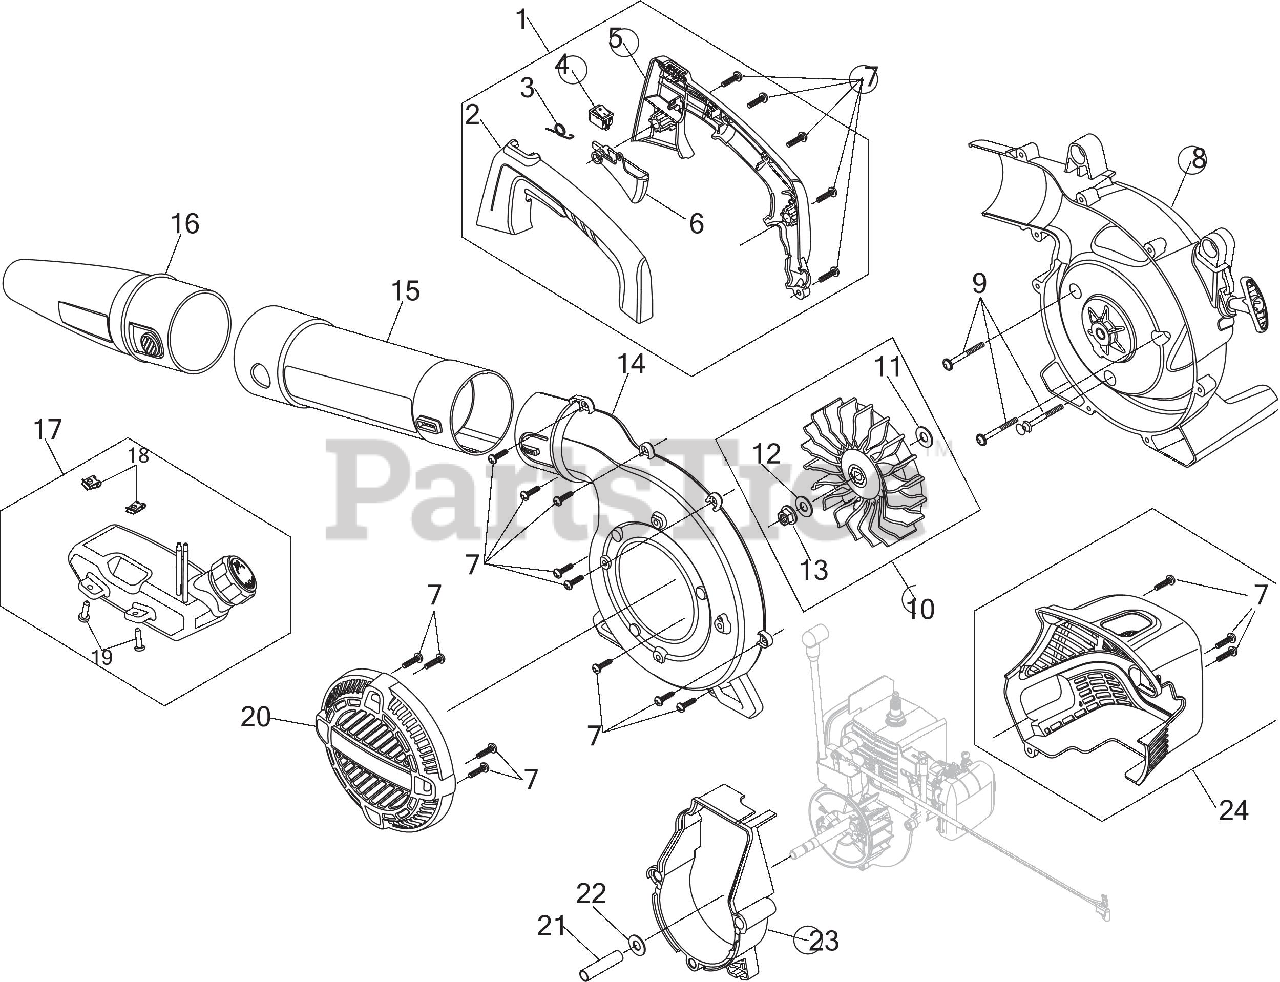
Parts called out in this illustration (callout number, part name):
1	HANDLE ASSEMBLY
2	HANDLE (LH)
3	TRIGGER SPRING
4	SW, MOMENTARY ON/O
5	HANDLE (RH)
7	SCREW 8-16 x 3/4
8	IMPELLER HOUSING ASSEMBLY (RH)
9	SCREW 10/32
10	IMPELLER ASSEMBLY
11	FLAT WASHER
12	LOCK WASHER
13	NUT 3/8-24
14	IMPELLER HSG ASSEMBLY (LH)
15	TUBE UPPER
16	NOZZLE
17	FUEL TANK ASSEMBLY
18	U-TYPE NUT
19	SCREW 10-6 x .75
20	INTAKE COVER
21	SPACER
22	FLAT WASHER
23	ENGINE ADAPTER
24	ENGINE CVR
